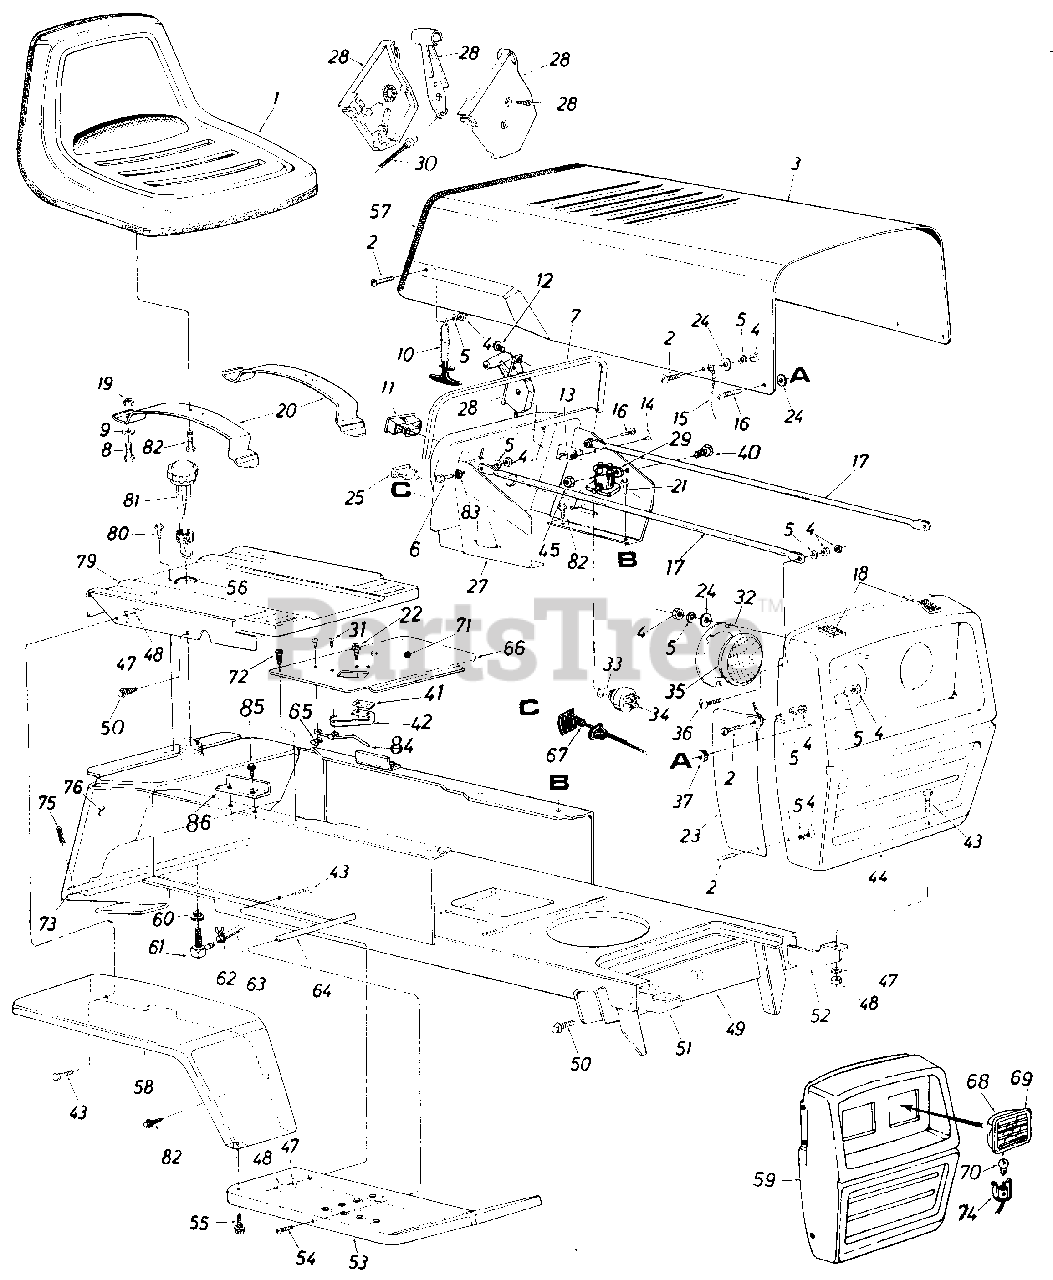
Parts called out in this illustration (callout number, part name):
1	Seat Assembly
2	Truss Mach. Scr. 1/4-20 x .50" Lg.*
5	L-Wash. 1/4" Scr.*
6	Truss Mach. Scr. 1/4-20 x 1" Lg.*
7	Vinyl Molding Strip-29"
8	Hex Nylon Scr. 1/2-13 x . 75 " Lg .
9	Fl-Wash 50" I.D. x 1.00" O.D x .090
10	Hood Latch Ass'y.
11	Ammeter
12	Truss Mach. AB-Tap Scr. #10 x .50" Lg.
13	Circuit Breaker 8 Amp.
14	Hex Tap Scr. #10 x .50" Lg.*
15	Hood Stop
16	Truss Mach. Scr. 1/4-20 x . 75 " Lg .*
17	Grille Positioning Rod
18	PVC Foam Strip 1/2 x 1.00" x 2.00" Lg.
19	Hex Nut '/2-13 Thd.*
22	Hex AB-Tap Scr. #8 x .5" Lg.
23	Grille Side Panel-R.H.
24	Fl-Wash. '/4" I.D.
25	Light Switch
27	Dash Panel Ass'y.
28	Throttle Control Box Comp.
29	Solenoid
30	Throttle Control Cable
31	Truss Hd. Scr. #10 x .50" Lg.
32	Head Lamp Retainer
33	Ignition Key
34	Ignition Switch
35	Head Lamp
36	Truss Machine Scr. 1/4-20 x .75" Lg.*
37	Rubber Wash. .50" I.D. x 1.00 O.D. x .25 Thk.
40	Hex Bolt 1/4-20 x .50" Lg.*
41	Insulator Nut Plate
42	Switch Spring
43	Hex Scr. 5/16-18 x .75" Lg.
44	Grille Ass'y. (Painted)
45	Hex Sems Nut 1/4-20 Thd.
47	L-Wash. 5/16" Scr.
48	Hex Nut 5/16-18 Thd.
49	Lower Frame Ass'y.
50	Hex Thd. Rolling Scr. 5/16" x.75" Lg.
51	Grille Mount Brkt.-R.H.
52	Grille Mount Brkt.-L.H.
53	Running Board-R.H.
54	Truss Mach. Scr. 5/16-18 x .75" Lg.
55	Hex Thd. Rolling Scr. 5/16-24 x .75" Lg.
56	Grommet
57	Vinyl Moulding Strip-30"
58	Fender Ass'y.-R.H.
59	Grille With Sq. Headlights
60	Bushing
61	90ø Nipple
62	Hose Clamp 3/8"
63	Gas Line 46" Lg.
64	Running Board Rod
65	Speed Nut #10-24 U-Type
66	Transmission Cover Ass'y.
67	Choke Control Comp.
68	Headlight Housing
69	Headlight Lens
70	Lamp
71	Snap Bushing
72	Truss Hd. Scr. #10 x .50" Lg.
73	Hitch Rod
74	Headlight Socket
75	Internal Cotter Pin
76	Gas Tank
79	Seat Plate
80	Hex Thd. Rolling Scr. 5/16-24 x .75" Lg.
81	Gas Gauge
82	Hex Thd. Rolling Scr. 5/16-24 x .75" Lg.
83	External Wash. 1/4" I.D.
84	Shift Lever Spring
85	Hex Thd. Rolling Scr. 5/16-18 x .62" Lg.
86	Seat Spring Guide
